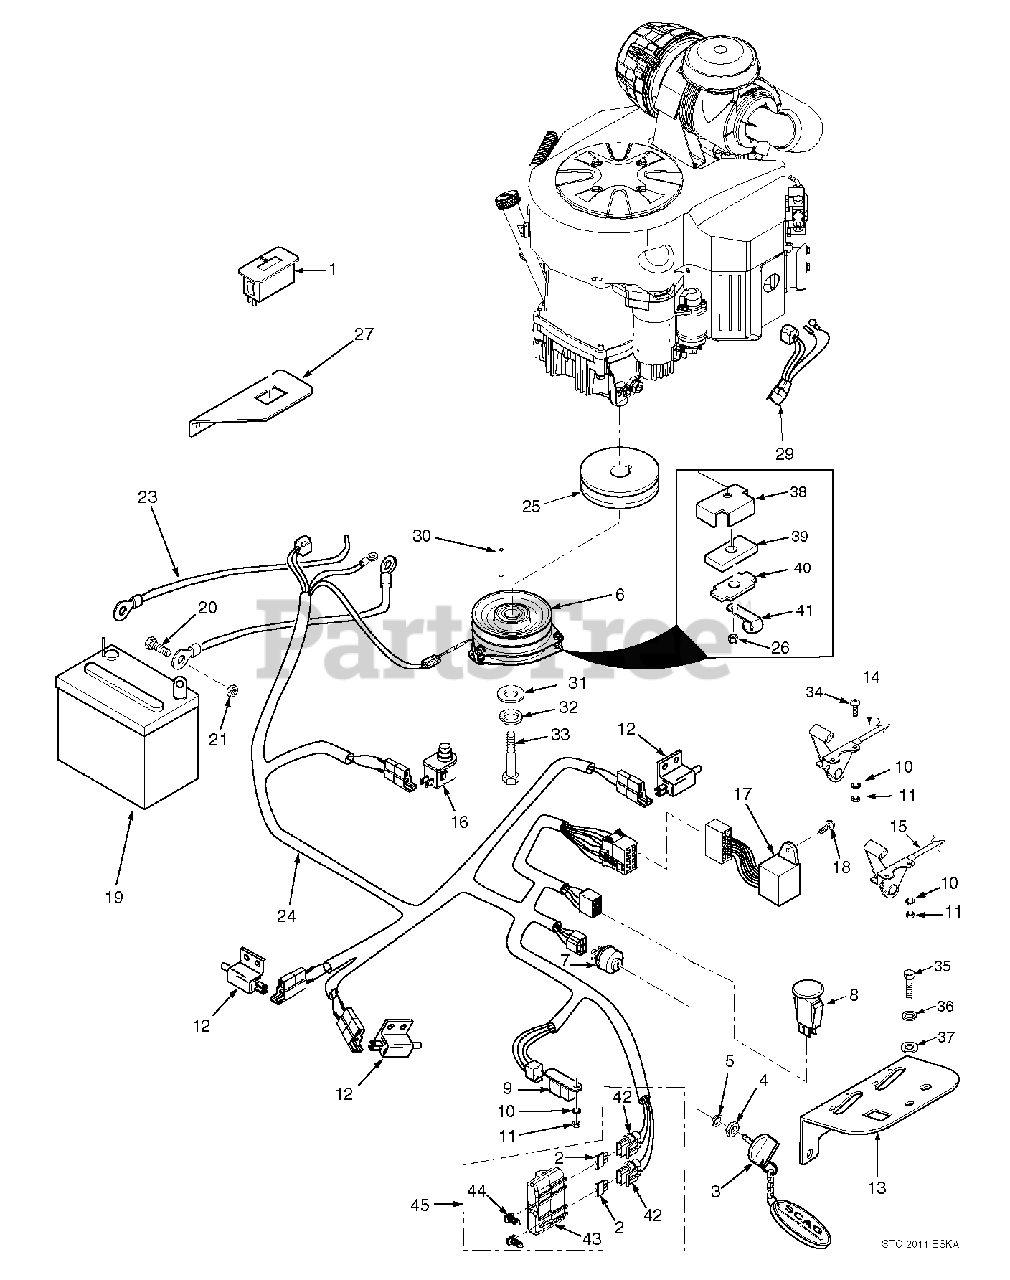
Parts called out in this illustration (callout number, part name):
1	Hourmeter
2	Fuse, 20 amp
3	Key, Ignition
4	Nut, Hex 5/8-32
5	Lockwasher, 5/8" Internal
6	Electric PTO Clutch GT3.5
7	Switch, Ignition
8	Switch, PTO
9	Relay
10	Lockwasher, #10 External Tooth
11	Nut, Hex #10-32
12	Switch, N/O
13	Panel, Instrument
14	Choke & Throttle Control
14	Choke Control
15	Throttle Control
16	Switch, Seat
17	Module, Interlock
18	Screw, #10-32 x .5" Phillips Head
19	Battery, 350CCA
20	Bolt, Hex Head 1/4-20 x .5"
21	Nut, Hex 1/4-20
22	Cable, Battery Black
23	Cable, Battery Red
24	Wiring Harness, Main
24	Wire Harness, Main
25	Pulley, 5.45 OD x 1.125" Bore
26	Nut, Elastic Stop 5/16-18 Key
27	Mounting Bracket, Hour Meter
28	Screw, #10-32 x 1.5" Phillips Head
29	Adapter, Wiring Harness
30	Key, 1/4 x 1/4 x 3-1/4"
31	Flatwasher, 7/16-.469 x 1-3/4" x 1/4"
32	Lockwasher, 7/16"
33	Bolt, Hex Head 7/16-20 x 2-1/2" UNF
34	Screw, #10-32 x 3/4"
35	Bolt, Hex Head 5/16-18 x 3/4"
36	Lockwasher, 5/16"
37	Flatwasher, 5/16-.375 x .875 x .083
38	Backing Plate
39	Rubber Pad, Clutch Stop
40	Plate, Backing
42	Fuse Holder
43	Cover, Sealed Double
